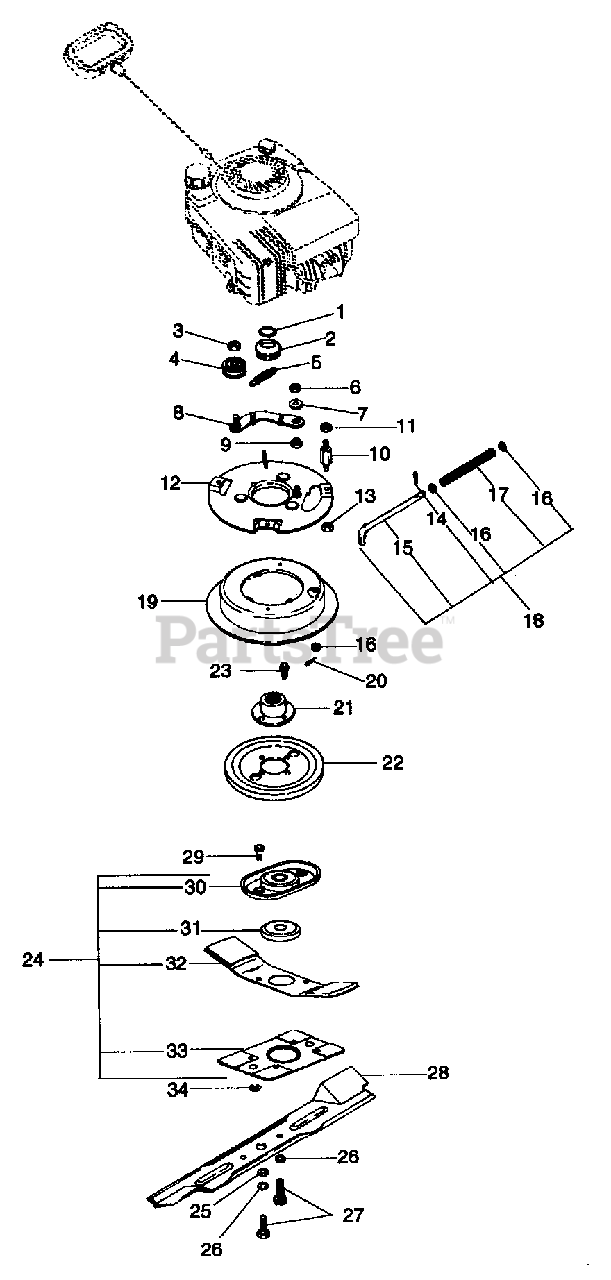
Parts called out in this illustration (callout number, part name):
1	RG-RTNG-EXT.875X.075
2	SHEAVE-BBC
3	NUT-LK-CTR .375-16 GR A PL
4	IDLER-FLAT 1.50 X .39 CLARK
5	SG-TENS .48X.44X2.0 5.0 WLD
6	NUT-LK .312-18 GR A PL
7	WSHR-FL-STL .328X1.0X.094 PL
8	IDLER ARM WELDMENT BBC
9	BSHG, FLG .325X.499X.26X.88
10	HEX STUD BBC
11	NUT-LK TOP .375-16 GR C YWZC
12	BBC RAMP ASSY
13	NUT-FLG. .312-18 PL
14	PIN-HAIR INT .06X.18X.77
15	ROD,RETURN BBC
16	WSHR-FL-STL .328X.555X.06 PL
17	SG-COMP .080X.550X8.50 WLD38
18	ROD RETURN ASSEM.
19	ACTUATOR,BRAKE
20	PIN-COTR .06X.50
21	FLYWHEEL HUB
22	FLYWHEEL
23	SCR-TAP .250-20X.50 HXSLHDPL
24	BBC LEAF SPRING AND BEARING AS
25	WSHR-FL-STL .382X1.25X.130
26	WSHR-LK .375X.115 HVY PL
27	BLT-HEX .38-24X1.25 PL GR5
28	BLADE, 21" MOWER
29	SCR-SKH 10-24X.50
30	BLADE MOUNT ASSEMBLY
31	BRG-BALL .984X2.047X.59
32	SPRING PAD ASSY
33	SPACER HUB WELDMENT
34	NUT-KEPS 10-24 PL
